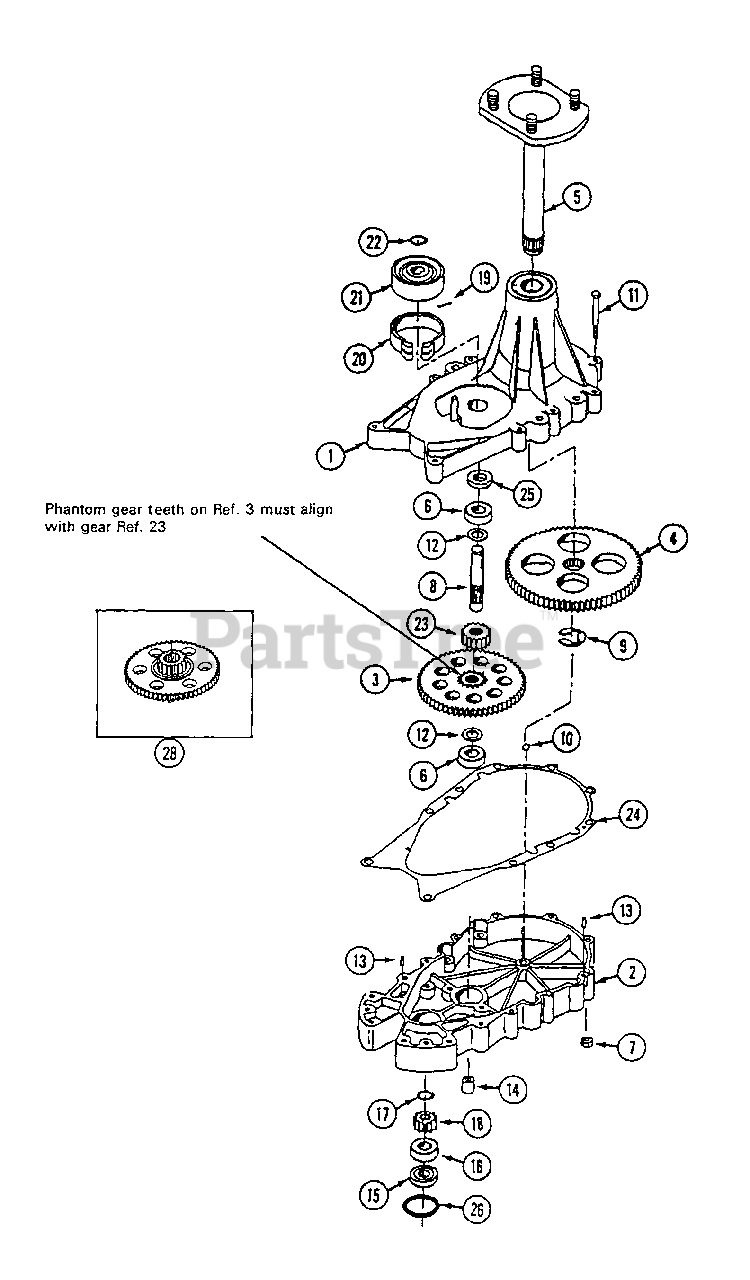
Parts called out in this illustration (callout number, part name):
1	HOUSING - axle
2	HOUSING - hydro mount
5	SHAFT - axle
7	NUT - 5/16" - 18
8	SHAFT - brake
9	RING - retaining
11	BOLT - 1/4" - 20 x 2-1/2"
11	BOLT - 5/16" - 18 x 2-3/4"
14	SPACER - mounting
15	SPACER - bearing
16	BEARING - ball
17	RING - retaining
19	PIN - cotter
22	RING - retaining
24	GASKET - housing
28	GEAR
